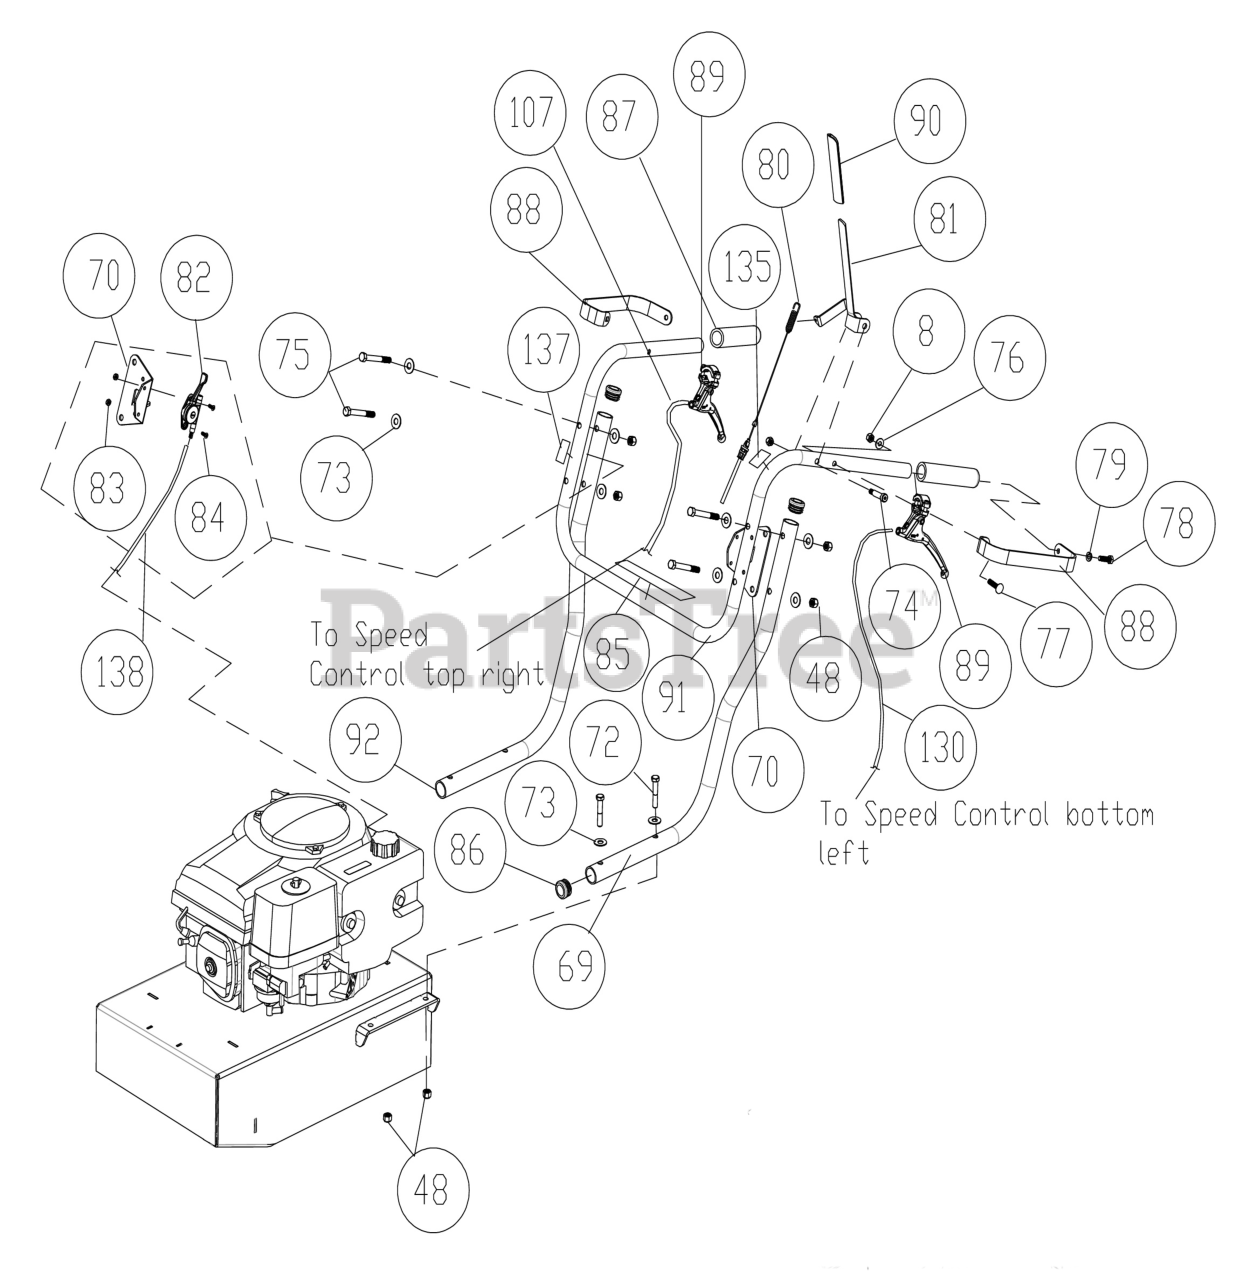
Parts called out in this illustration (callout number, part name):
8	NUT LOCK 5/16"-18 HEX Z/P
48	NUT LOCK 3/8"-16 HEX
69	HANDLE, LOWER LEFT PAINTED
70	BRACKET THROTTLE BC26
72	SCREWCAP 3/8"-16X2" HCS ZP
73	WASHER 3/8"FC7/16"X1"X5/64"
74	BOLT SHOULDER 3/8 X 1 1/2"
75	SCREWCAP 3/8"-16X3" HCS ZP
76	WASHER 1/4" FLAT Z/P
77	BOLT CARRIAGE 5/16"-18X1 1/2" ZP
78	SCREWCAP 5/16"-18 X 1" HCS ZP
79	WASHER LOCK 5/16 ST MED
80	CABLE CLUTCH
81	SEE: 500312-S
82	CONTROL THROTTLE BLOWER
83	NUT LOCK LT #10-24 HEX
84	SCREW MACHINE FLAT HD PHIL #10-24
85	LABEL DRIVE DIRECTION
86	PLUG TUBE INSERT 1.25" O.D.
87	GRIP HANDLE
88	GUARD HAND BC2600
89	CONTROL MAGURA
90	GRIP LEVER 0.125" X 1" X 5" ORANGE
91	HANDLE UPPER WITH GRIPS & LABELS BC 26 HYDRO
92	HANDLE LOWER RIGHT
107	SEE: 501276-S
130	SEE: 351271-S
135	LABEL CLUTCH BLADE
137	LABEL THROTTLE BC
138	CABLE THROTTLE BLOWER
